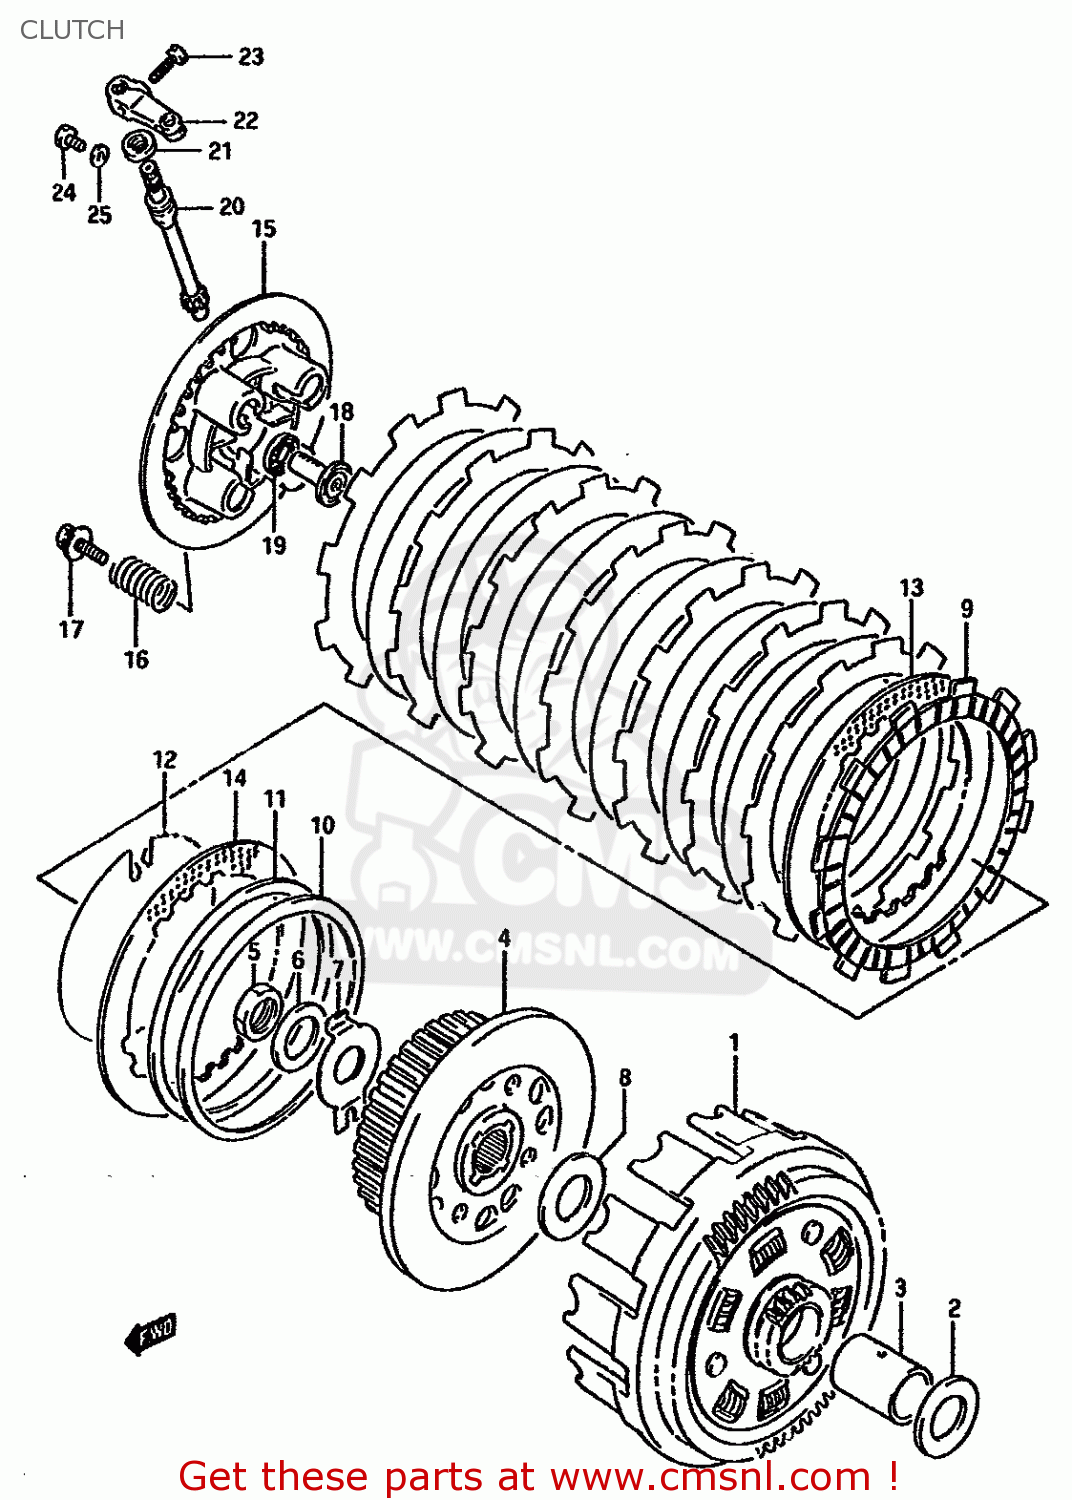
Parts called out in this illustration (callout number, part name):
1	GEAR,PRIMARY DRIVEN (NT:62/20)
2	WASHER(22X38X2)
3	SPACER
4	HUB,CLUTCH SLEEVE
5	NUT (20MM)
6	WASHER
7	WASHER
8	WASHER(22X44X2)
9	PLATE,CLUTCH DRIVE (MCA)
10	SEAT,WAVE WASHER
11	WASHER
12	RING,STOPPER
13	PLATE,CLUTCH DRIVEN NO.1 (NAS)
14	PLATE,CLUTCH DRIVEN (NAS)
15	DISK,PRESSURE
16	SPRING
17	BOLT
18	RACK,CLUTCH RELEASE
19	BEARING(10X22X2.8)
20	PINION,CLUTCH RELEASE
21	SEAL,OIL(10X17X5)
22	ARM,CLUTCH RELEASE
23	BOLT
24	BOLT
25	GASKET(6.2X11X1).2 (NAS)
